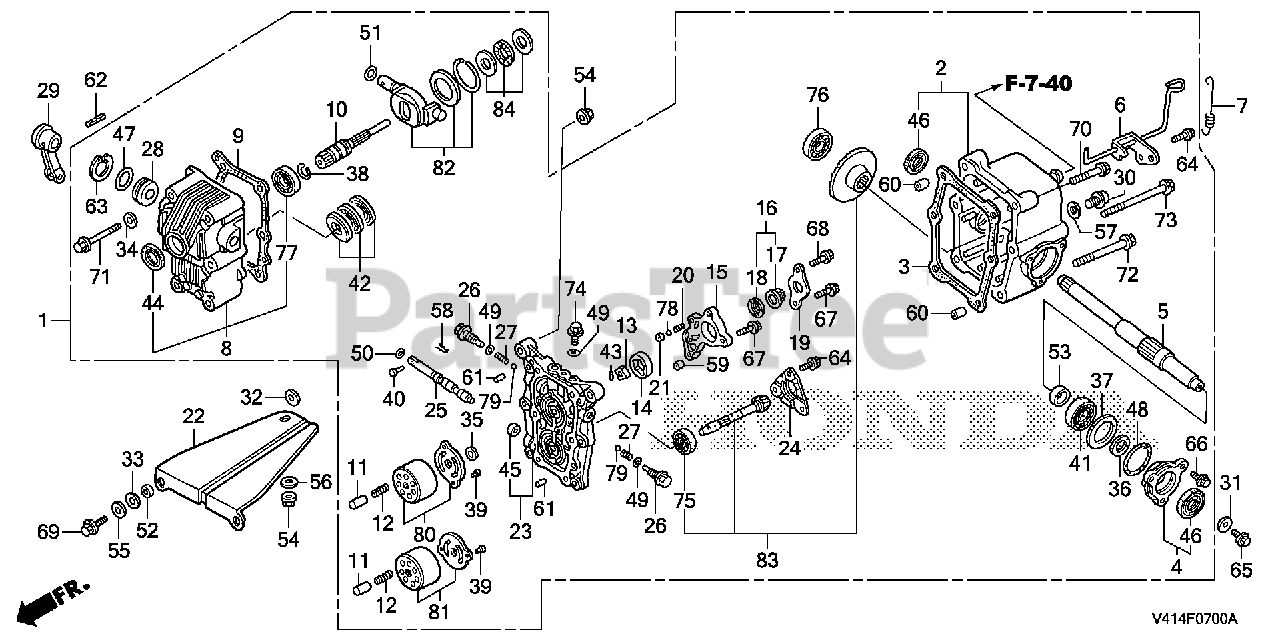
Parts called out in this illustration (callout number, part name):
1	TRANSMISSION ASSY.
2	CASE, RR. TRANSMISSION
3	GASKET, RR. TRANSMISSION CASE
4	HOLDER, OIL SEAL
5	SHAFT, CROSS
6	ARM, NEUTRAL VALVE
7	SPRING, NEUTRAL VALVE
8	CASE, PUMP
9	GASKET, PUMP CASE
10	SHAFT, PUMP
11	PISTON, PUMP (HOLE DEPTH=18MM)
12	SPRING, PISTON (5.8X34.5)
13	ROTOR, TROCHOID
14	VANE, TROCHOID
15	HOUSING, TROCHOID
16	FILTER ASSY., SUCTION
17	FILTER, SUCTION
18	SEAL, RUBBER
19	PLATE, FILTER CAP
20	SPRING, RELIEF VALVE
21	SEAT, RELIEF VALVE
22	PLATE, TRANSMISSION MOUNTING
23	PLATE, DISTRIBUTOR
24	HOLDER, BEARING
25	SPOOL, NEUTRAL VALVE
26	BOLT, CHECK VALVE
27	SPRING, CHECK VALVE
28	BUSH, CONTROL BOWL (B)
29	ARM, CLUTCH
30	BOLT, PLUG (14MM)
31	WASHER (6X17)
32	WASHER (8MM)
33	WASHER, WAVE (12MM)
34	WASHER, SEALING (9X16X1.5)
35	WASHER, THRUST (8MM)
36	WASHER, PLAIN (15MM)
37	SHIM A, BEVEL GEAR (1.5MM)
37	SHIM B, BEVEL GEAR (1.55MM)
37	SHIM C, BEVEL GEAR (1.6MM)
37	SHIM D, BEVEL GEAR (1.65MM)
37	SHIM E, BEVEL GEAR (1.7MM)
37	SHIM F, BEVEL GEAR (1.75MM)
38	CLIP, BEARING
39	PIN, DOWEL (3X5.8)
40	PIN, NEUTRAL VALVE
41	BEARING, RADIAL BALL (6904) (NTN CORP.)
42	BEARING, THRUST BALL (51204)
43	ROLLER (2.5X11.8)
44	OIL SEAL (17X30X5) (NIPPON)
45	DUST SEAL (9X15X5)
46	OIL SEAL (15X28X7)
47	O-RING (25X2.4)
48	O-RING (34.6X1.9)
49	O-RING (11X1.9)
50	O-RING (5.8X1.9)
51	O-RING (11.8X1.9)
52	COLLAR, TRANSMISSION MOUNT (8X12X4.7)
53	COLLAR, BEVEL GEAR
54	NUT, FLANGE (8MM)
55	WASHER, PLAIN (8MM)
56	WASHER, PLAIN (8MM)
57	WASHER, DRAIN PLUG (14MM)
58	PIN, LOCK (4MM)
59	PIN A, DOWEL (8X10)
60	PIN, DOWEL (10X12)
61	PIN, DOWEL (5X8)
62	PIN, SPRING (4X28)
63	CIRCLIP (INNER) (30MM)
64	BOLT, FLANGE (6X12) Use from Engine SN 2086984.
65	BOLT, FLANGE (6X16) Use from Engine SN 2056820.
66	BOLT, FLANGE (6X16)
67	BOLT, FLANGE (6X25)
68	BOLT, FLANGE (6X32)
69	BOLT, FLANGE (8X40) Use up to Engine SN 1003236.
70	BOLT, FLANGE (8X45)
71	BOLT, FLANGE (8X65)
72	BOLT, FLANGE (8X70)
73	BOLT, FLANGE (8X90)
74	BOLT, FLANGE (10X16)
75	BEARING, RADIAL BALL (6001)
76	BEARING, RADIAL BALL (6002)
77	BEARING, RADIAL BALL (6003)
78	BALL, STEEL (#6) (3/16)
79	BALL, STEEL (#8) (1/4)
80	PLATE SET, PUMP CYLINDER
81	PLATE SET, MOTOR CYLINDER
82	BOWL SET, CONTROL
83	GEAR SET, MOTOR SHAFT & BEVEL
84	BEARING SET, THRUST NEEDLE
